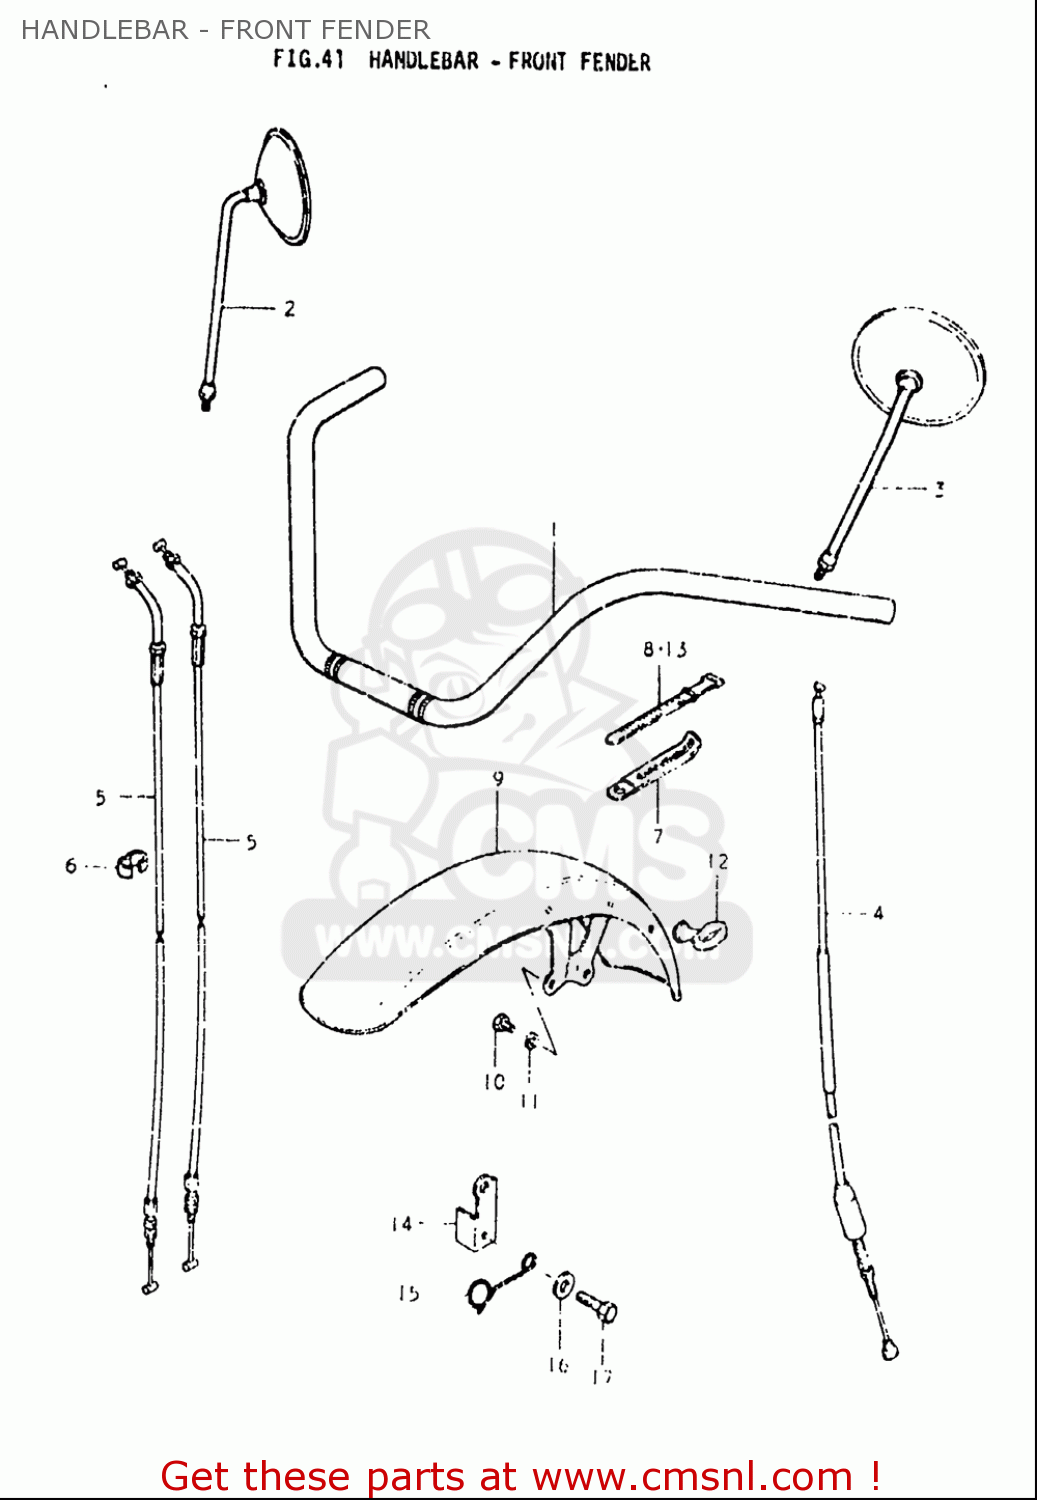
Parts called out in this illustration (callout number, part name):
1	HANDLEBAR
2	MIRROR ASSY,RR VIEW,R
3	MIRROR ASSY,RR VIEW,L
4	CABLE ASSY,CLUTCH
6	CLIP
7	CLAMP(L:65)
8	CLAMP
9	FENDER,FR
10	BOLT
11	WASHER,LOCK
12	GUIDE,CABLE
13	CLAMP(L:120)
15	GUIDE,SPEEDOMETER CABLE
16	WASHER
17	BOLT
